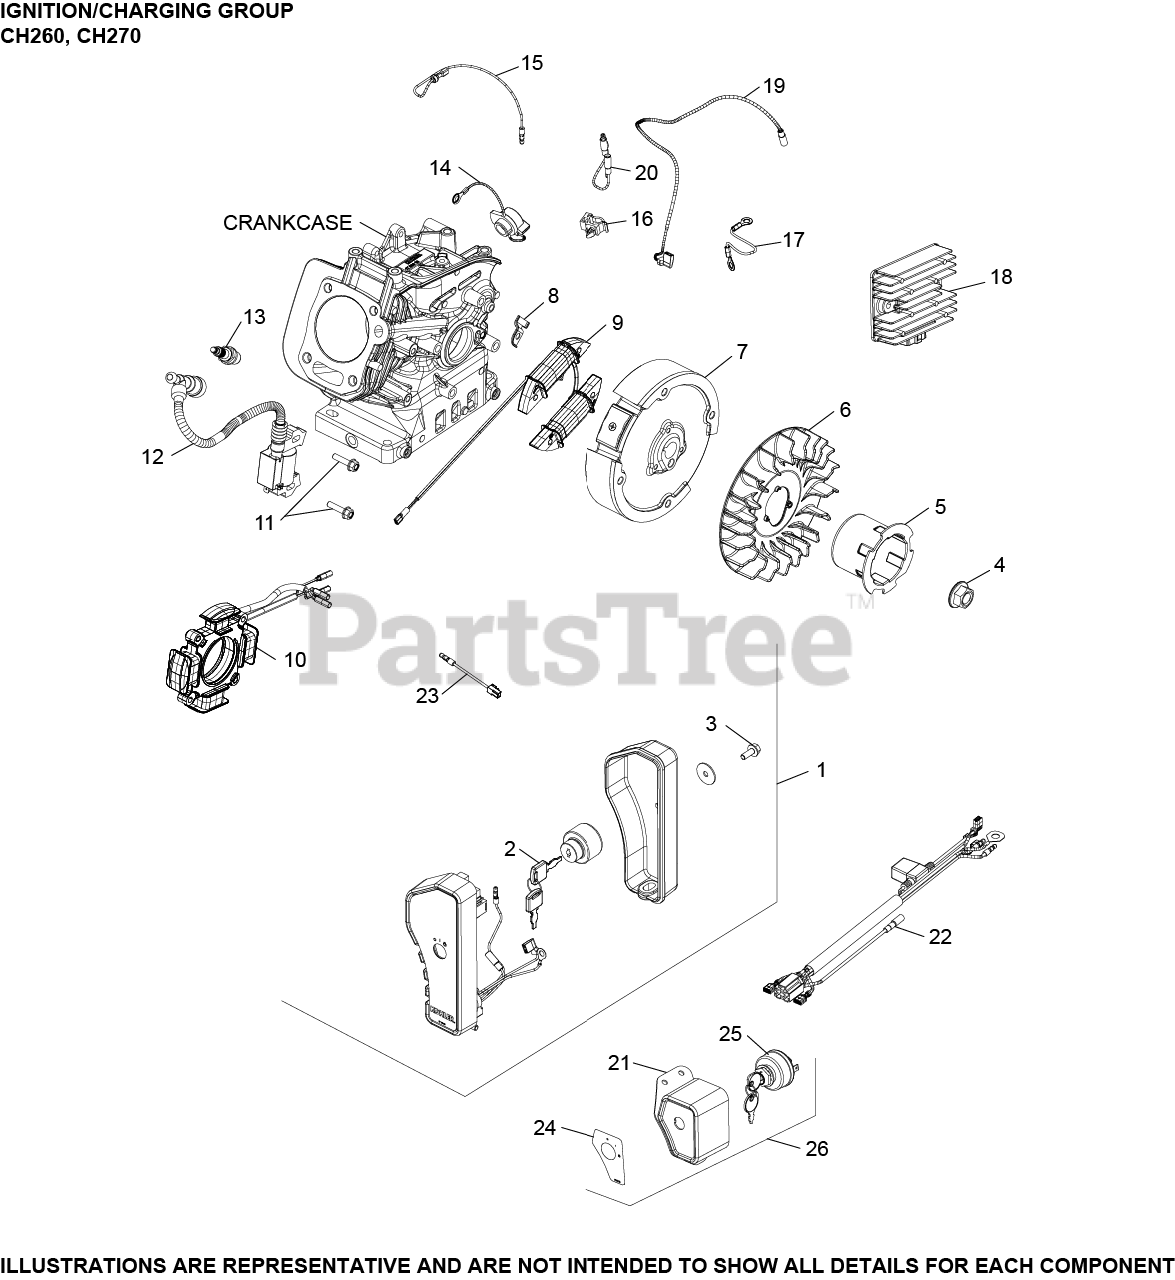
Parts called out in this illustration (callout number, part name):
4	NUT, FLYWHEEL
5	CUP, STARTER DRIVE
6	FAN, FLYWHEEL
7	FLYWHEEL ASSEMBLY, CAST IRON USE 17 025 28-S
11	SCREW, M6 X 25 USE 25 086 436-S
12	MODULE, IGNITION
13	SPARK PLUG
14	SWITCH, IGNITION
16	CLIP, WIRE HARNESS
19	LEAD, GROUND TO KILL
